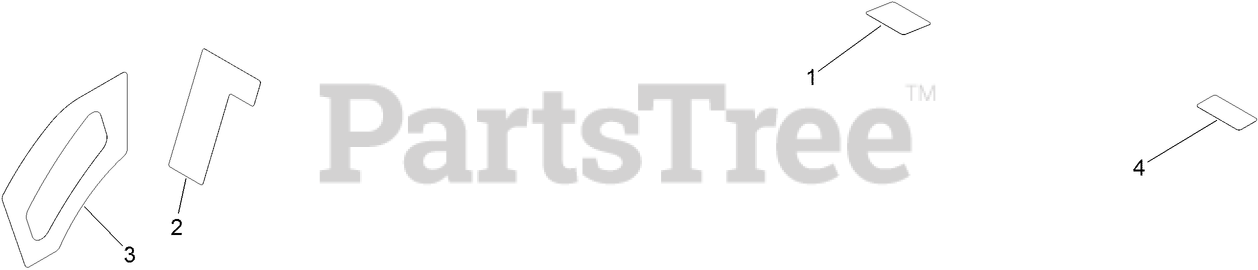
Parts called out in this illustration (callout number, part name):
1	DECAL-MAINTENANCE
2	DECAL-SMART SPEED
3	DECAL-HOC
4	DECAL-LOCATION, SERVICE DEALER
